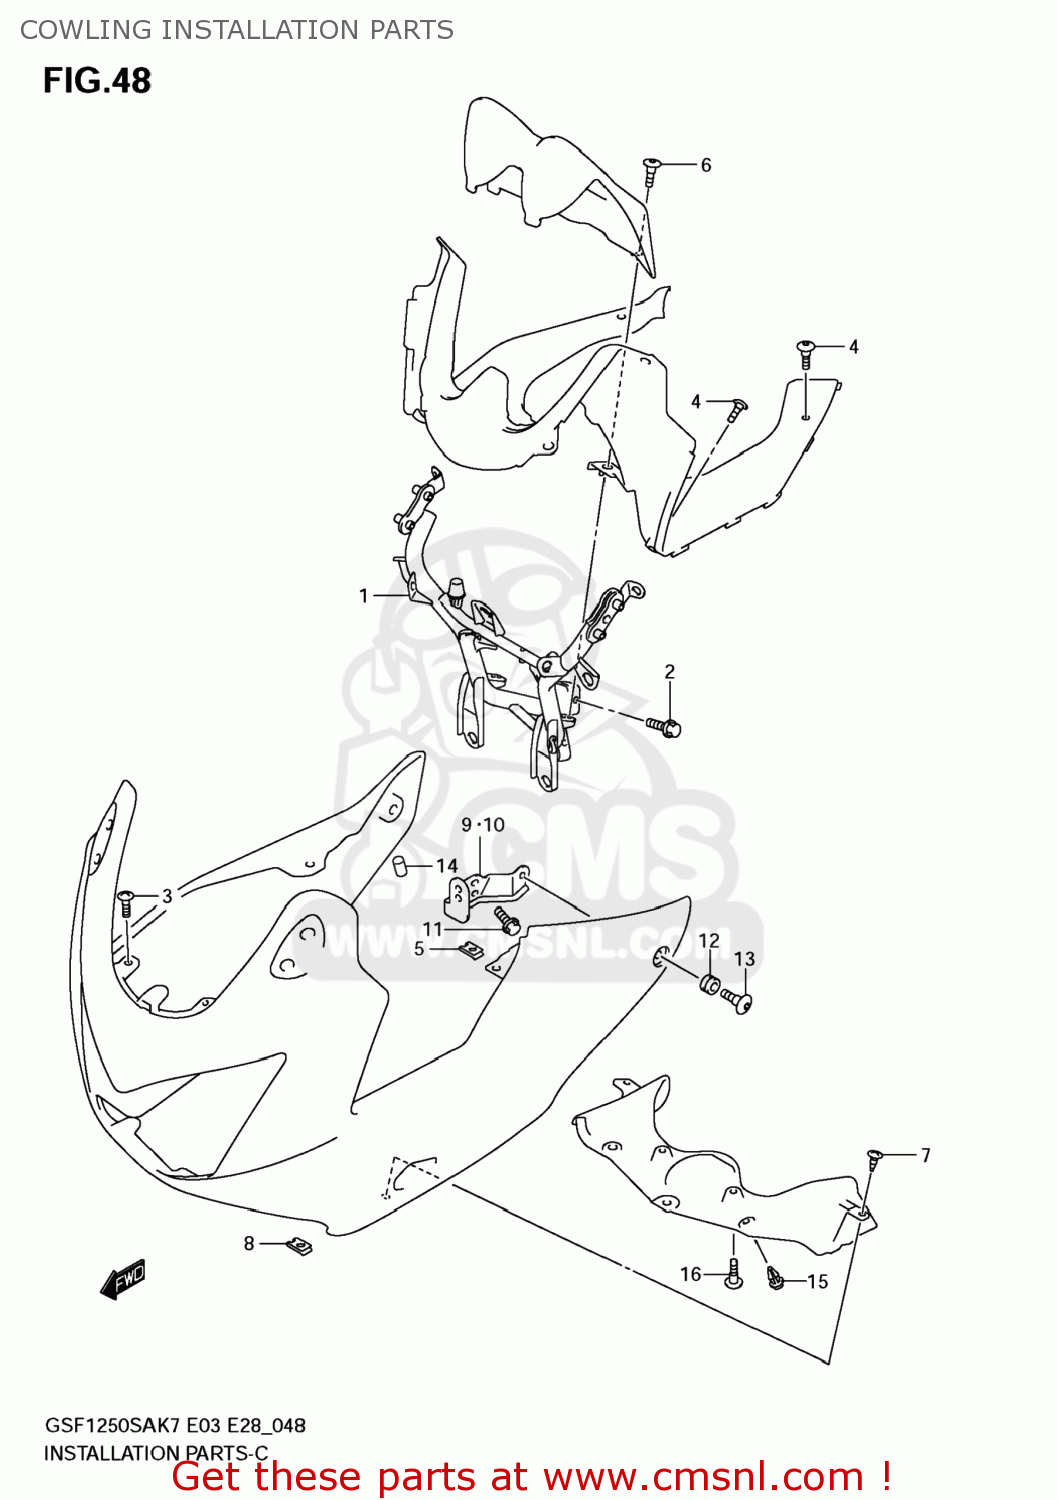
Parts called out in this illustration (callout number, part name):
1	BRACE COMP,COW
2	BOLT
3	SCREW
4	SCREW(5X13)
5	NUT,COWL
6	SCREW(5X16)
7	SCREW
8	NUT
9	BRACKET,COWLING FITTING,R
10	BRACKET,COWLING FITTING,L
11	BOLT
12	CUSHION
13	SCREW(6X20)
14	CAP
15	CLIP(BLACK)
16	BOLT(5X13)
